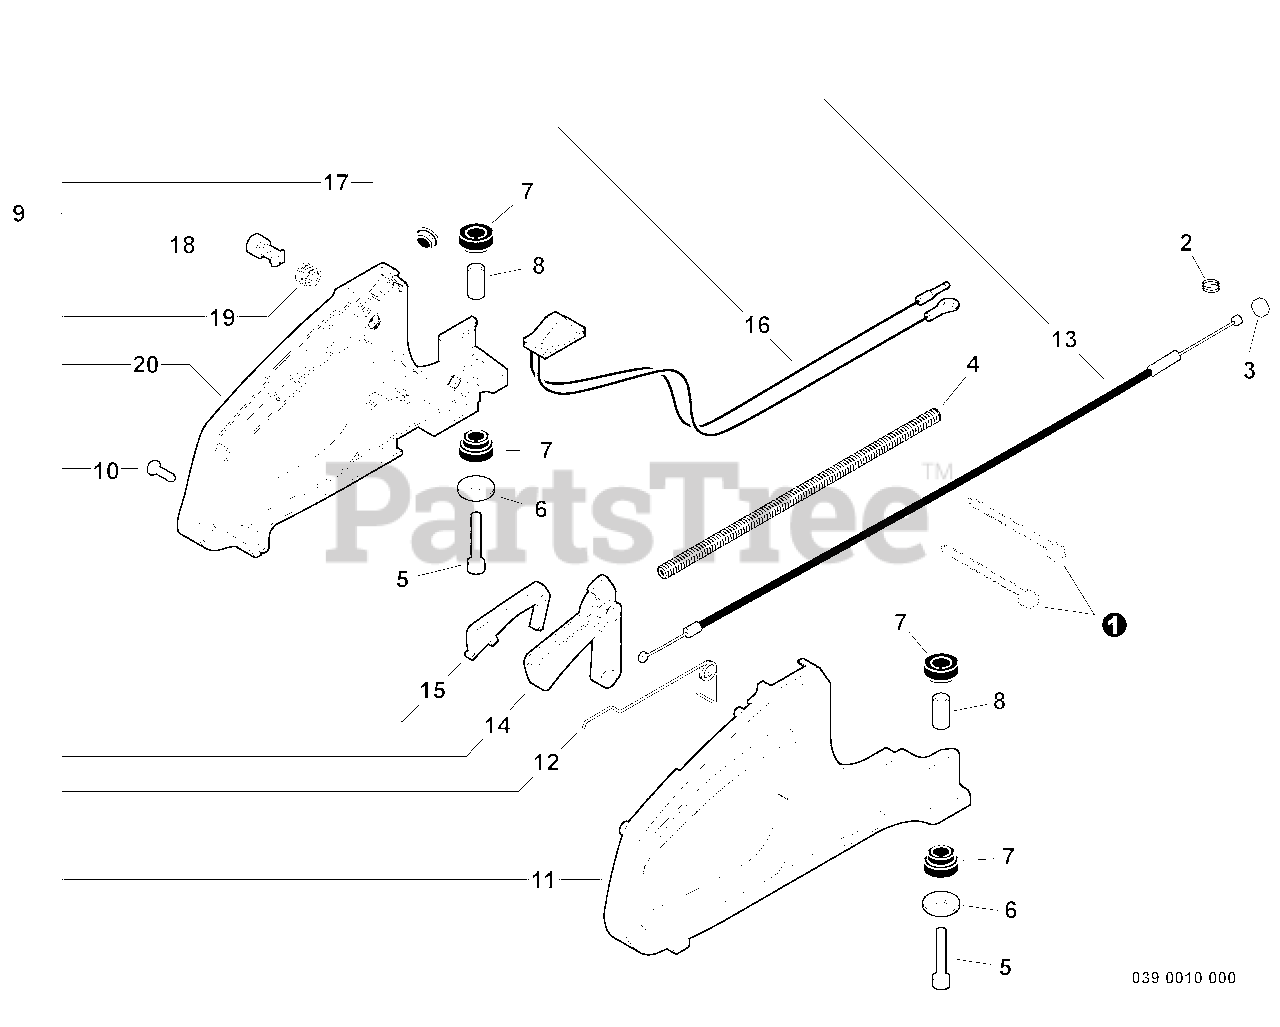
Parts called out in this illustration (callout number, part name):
1	STRAP, TIE
4	TUBE, FLEXIBLE
5	BOLT M6×35
6	WASHER Ø23ר6.5×2 MM
7	CUSHION
8	COLLAR 6
9	HANDLE ASSY, REAR
10	SCREW, TAPPING Ø4×18
11	CONTROL HANDLE - RIGHT
12	SPRING, THROTTLE RETURN
13	CABLE, THROTTLE
14	TRIGGER, THROTTLE
15	LEVER, THROTTLE LOCKOUT
16	SWITCH, ON-OFF
17	PLUG, RUBBER
18	BUTTON, THROTTLE LOCK
19	SPRING, COMPRESSION
20	CONTROL HANDLE - LEFT
